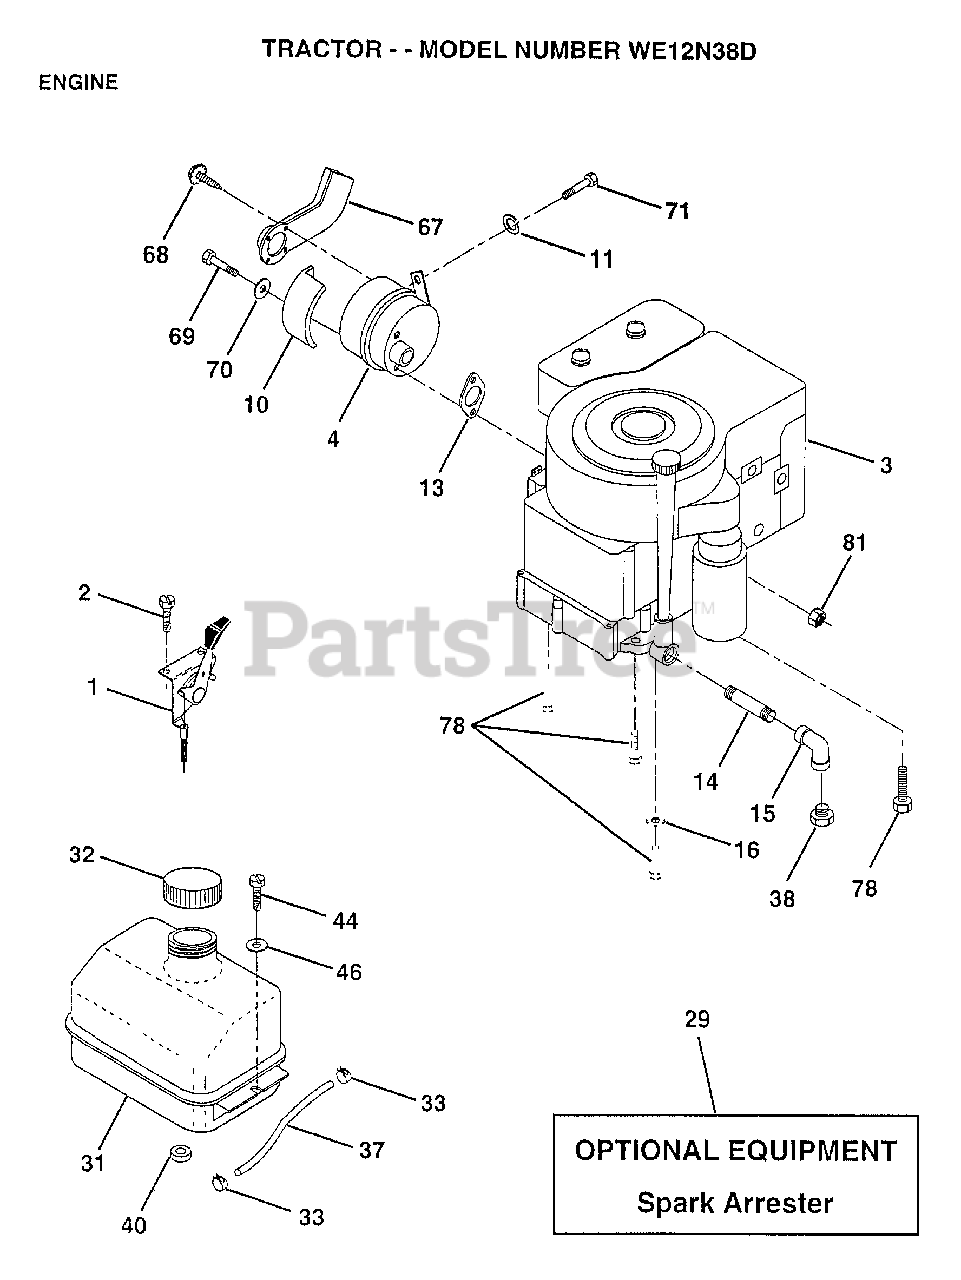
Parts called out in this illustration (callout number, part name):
1	THROTTLE CONTROL
2	SCREW LT
4	MUFFLER LTV
10	SHIELD HEAT LTV
11	LOCKWASHER
13	GASKET ENG 1 313 LD TIN PLATED
14	PIPE NIPPLE
15	ELBOW
16	LOCKWASHER
31	TANK.FUEL.LT.
32	CAP ASM FUEL
33	HOSE CLAMP
37	LINE FUEL
44	SCREW HEX CRT
46	WASHER
67	DEFLECTOR MUFFLER
69	"BOLT,HEX"
70	WASHER T
71	BOLT HXHD FIN
78	SCREW
81	NUT
